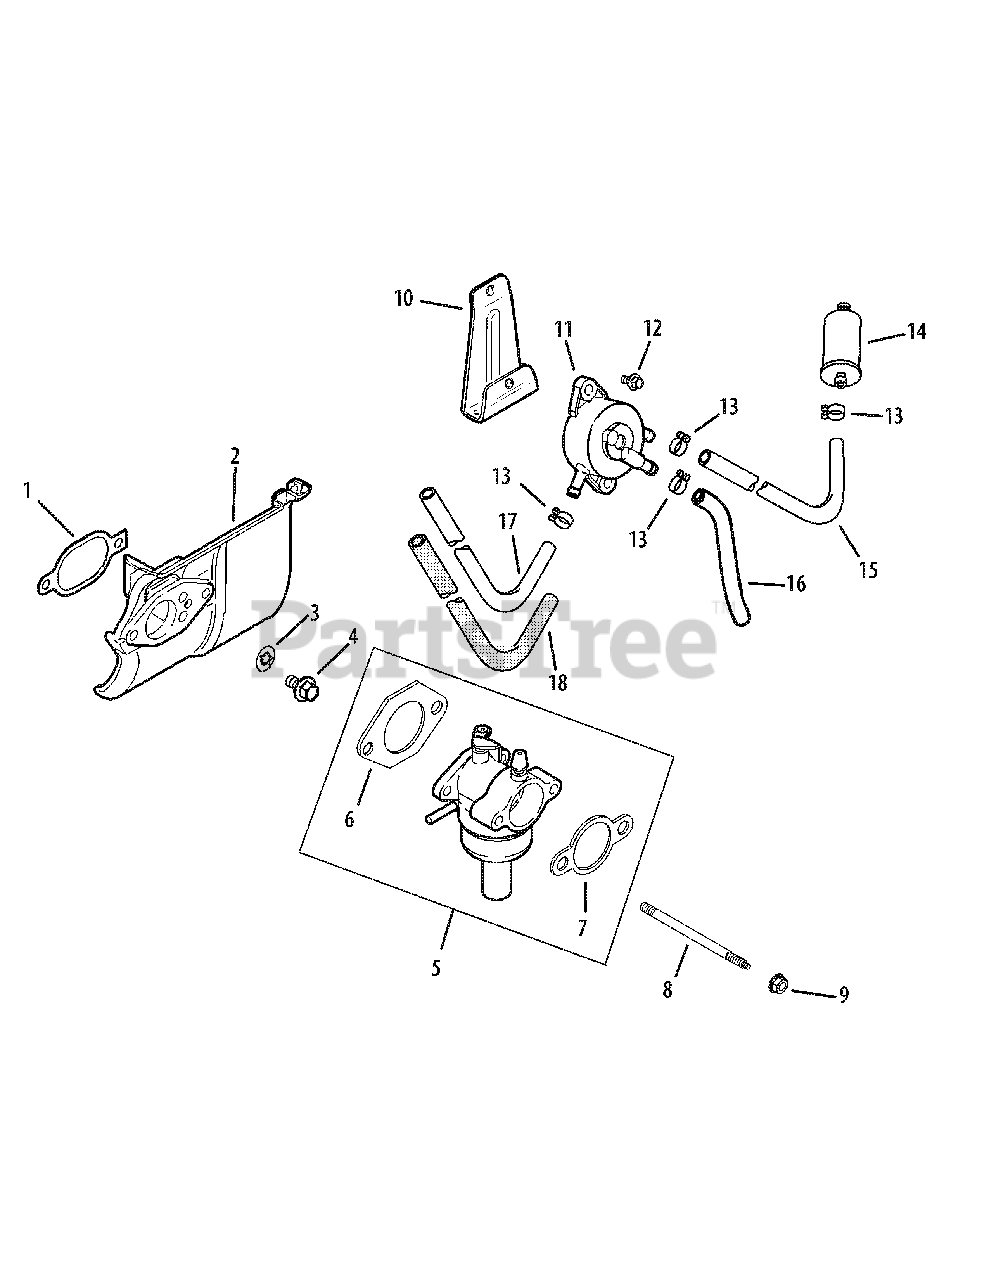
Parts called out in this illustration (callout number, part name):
1	Gasket, heat deflector
2	Deflector, heat
3	Washer, Int. Tooth Lock, 1/4"
4	Screw, hex. flange M6x1.0x20
5	Carburetor w/gaskets
6	Gasket, carburetor
7	Gasket, air cleaner
8	Stud, carburetor mounting
9	Nut, hex. flange M6x1.0
10	Bracket, fuel pump mounting
12	Screw, hex. flange
13	Clamp, hose
14	Filter, fuel
15	Line, fuel 15.75"
16	Line, fuel 4"
17	Line, fuel 10"
18	Sleeve, Anti-Abrasion
